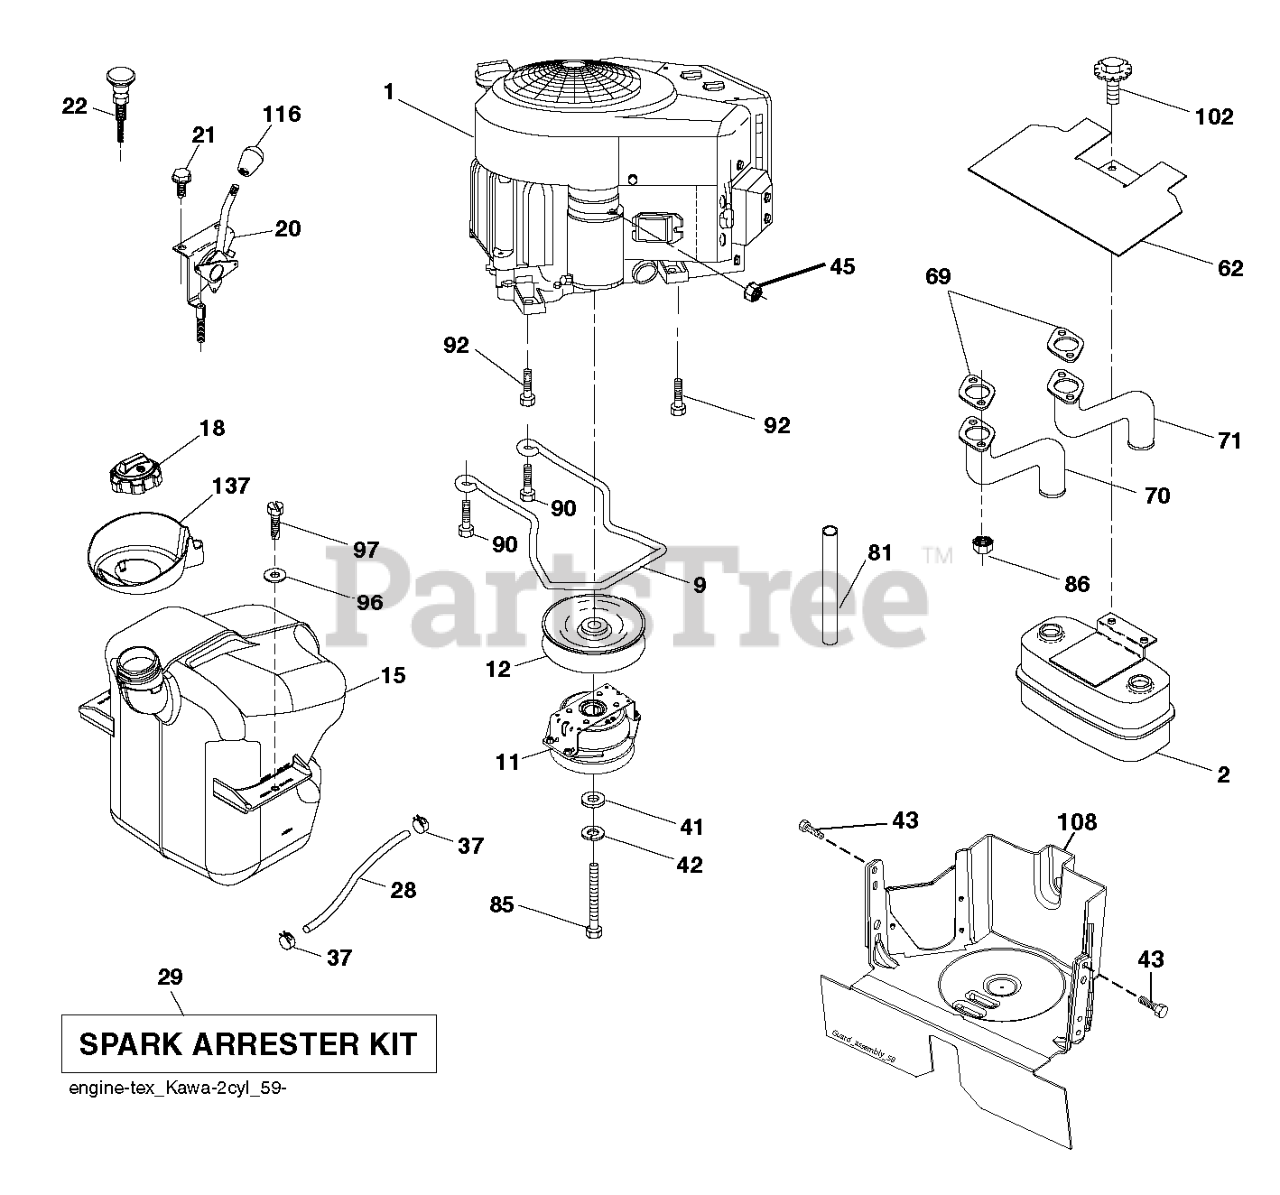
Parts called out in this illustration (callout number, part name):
2	MUFFLER.ASM.TWIN.MNTG.BRACKET
9	KEEPER.BELT.ENG.4.25"2.BLT.431
11	CLUTCH.OGURA.5.0PD.GT1.5A-EH07
12	PULLEY.ENGINE.TUFFTORQ
15	FUEL TANK TANK. ASSEMBLY. EXTE
18	CAP.ASM.FUEL.2.25"TOP.TURN
20	CONTROL.THROTTLE.PRO.
21	SCREW.#10 X 0.750.BOS
22	CONTROL, CHOKE
28	HOSE 1/4" LOW PERMEATION FUEL
29	KIT.SPARK ARRESTOR 794945 B&S
37	HOSE CLAMP
42	WASHER 7/16 LOCK
43	SCREW 5/16-18X1
45	NUT
62	SHIELD.HEAT.MUFFLER
70	TUBE.EXHAUST.LH.FR961/FR730
71	TUBE.EXHAUST.RH.FR961/FR730
81	TUBE, DRAIN OIL ASM.
85	BOLT.HEX.7/16-20X3.75.GR5.RED
86	NUT.HEX.FLANGE.TOPLOCK
90	SCREW 3/8-16X1
92	SCREW 3/8-16X1
97	SCREW HEXWSHR 1/4-20X3/4
102	SCREW
108	COVER ENGINE PULLEY COVER WITH
116	KNOB - SHIFT
